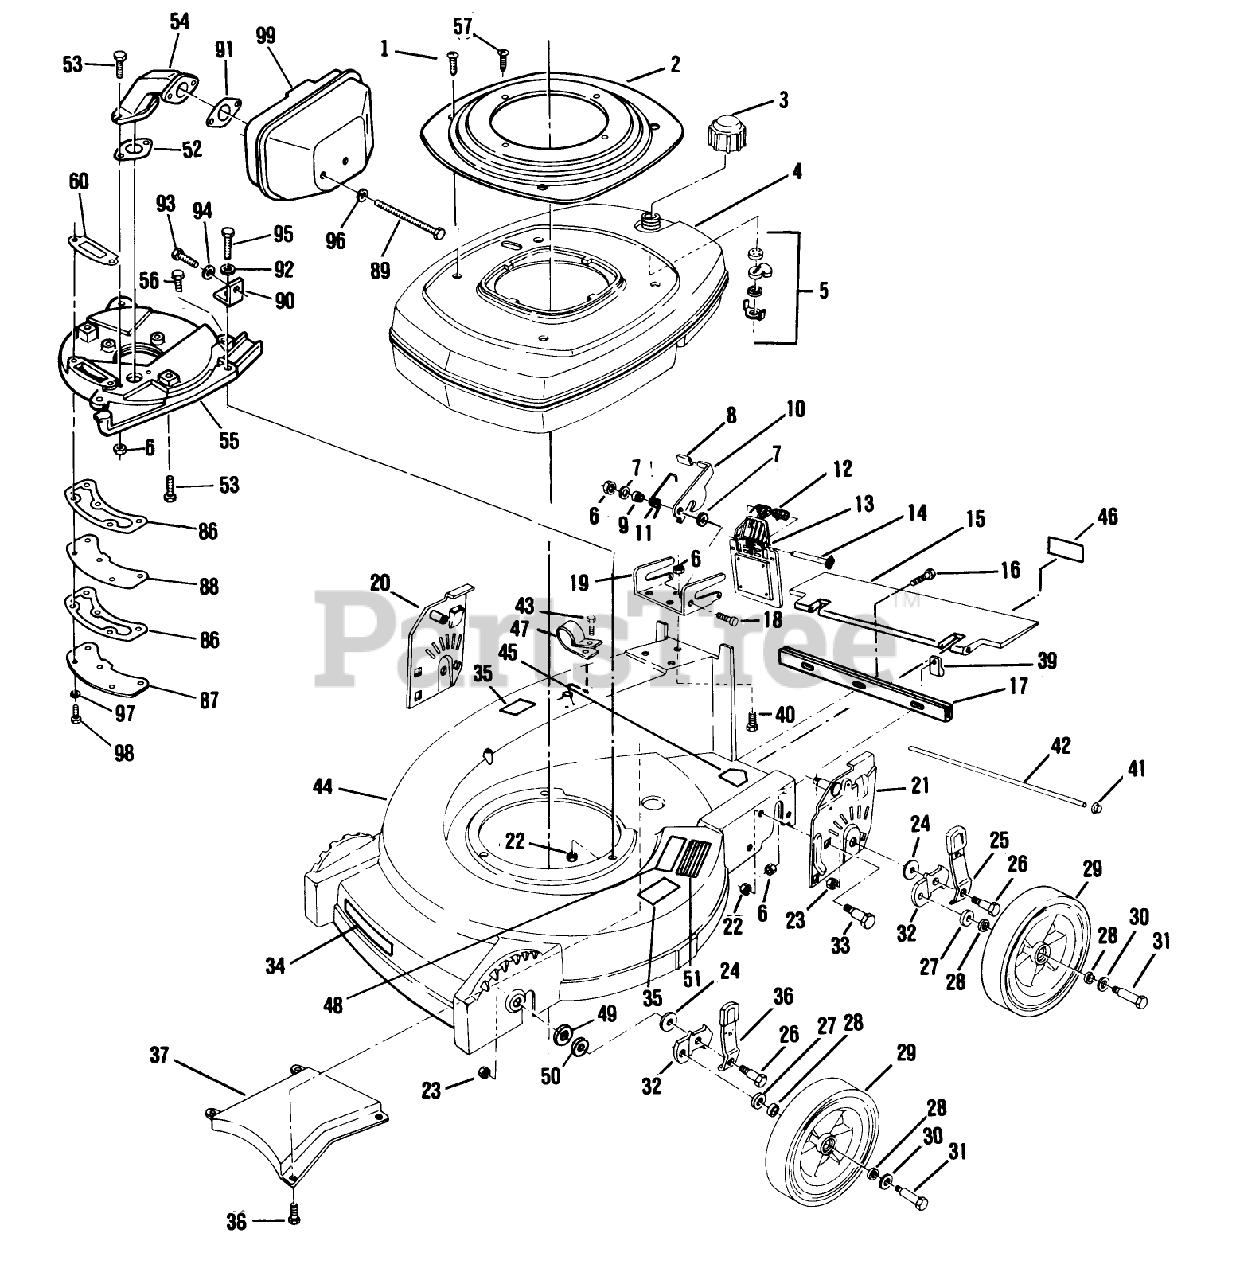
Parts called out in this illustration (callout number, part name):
3	FUEL CAP & INSERT
5	SHUT-OFF VALVE S
6	LOCKNUT E
8	KNOB (S&R)
11	SPRING
12	SPRING ASOC
14	ROD (RB&W)
15	T/SHIELD SM&P
22	NUT-LOCK F
23	LOCKNUT
24	WASHER
26	BOLT
27	WASHER WROUGHT
28	WASHER
30	SPACER
31	BOLT WHEEL
36	SPRING ARM ASM
37	BAFFLE CHUTE PL
43	SCREW LAWRENCE
49	WASHER
50	WASHER
51	PAD FOOT
56	SCREW
57	SCREW SEMS SM
58	SCREW V
86	GASKET S
87	COVER HIP
91	GASKET S
93	SCREW-SEMS
94	WASHER
95	SCREW
